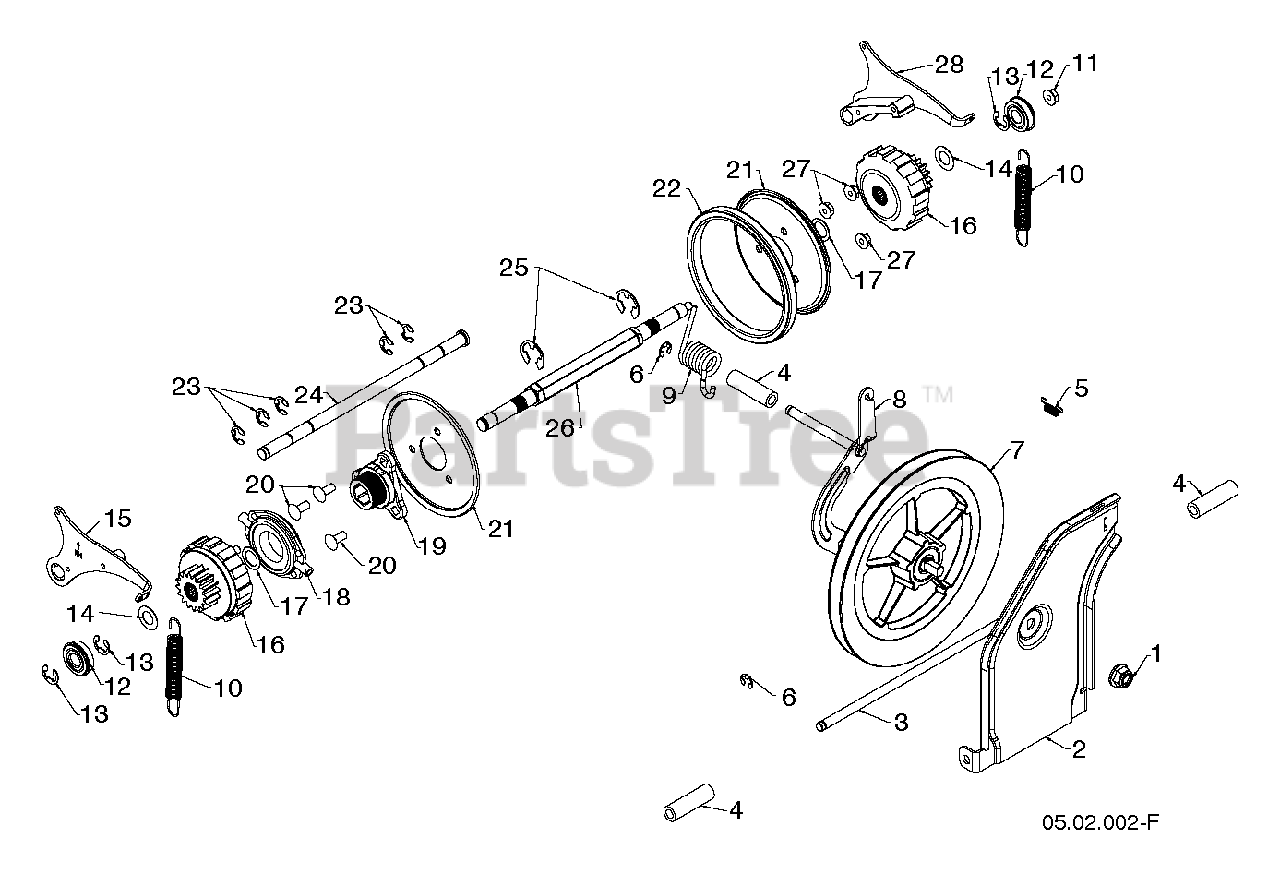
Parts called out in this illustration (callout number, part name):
1	NUT, 1/2-13 HEX FLG NYLOC ZD
2	PLATE.SWING.FRICTION PULLEY.47
3	ROD.TIP.PLATE
4	SPACER YOKE, TORSION SPRING
5	SPRING LATCH
6	E-RING LT
7	PULLEY.FRICTION.DISC.COMBO
8	BRACKET.YOKE.ASSEMBLY.479
9	SPRING TORSION DRIVE
10	SPRING EXTENSION PS
11	NUT.HEX.FLANGE.LOCK.5/16-18
12	BEARING 9/16 ID. SNR
13	RING RING, RETAINING RING (996
14	WASHER FLAT.637IDX1.00ODX21GA
15	PAWL.ASM.RH.SNOW
16	GEAR.ASM.PLANETARY
17	WASHER FLAT.59IDX1.065ODX25GA
18	TRUNNION BEARING ASSY
19	HUB.RUBBER.WHEEL
20	BOLT.CARR.SQNK.5/16-18UNC.X3/4
21	PLATE.RUBBER.WHEEL.BLACK
22	RING RUBBER
23	CLIP E-RING_.500 SHAFT
24	ROD ROD, PAWL ROD
26	SHAFT SHAFT, PWR STR SHAFT
27	NUT.LOCK.5/16-18
28	PAWL.ASM.LH.SNOW
